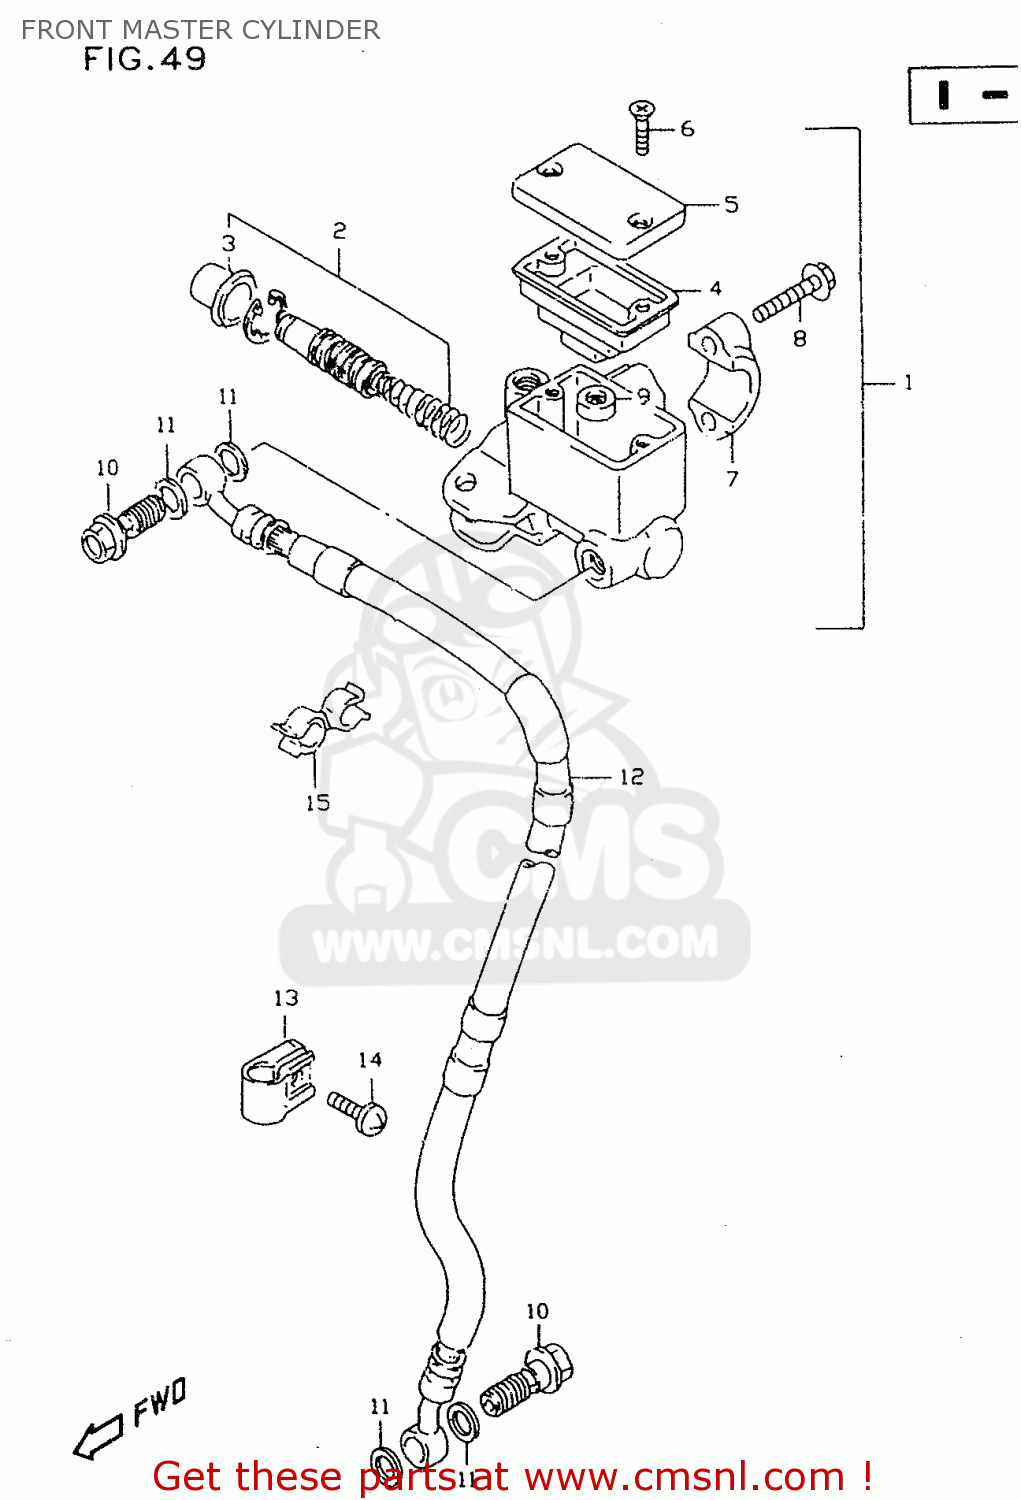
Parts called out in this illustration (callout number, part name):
1	CYLINDER ASSEMBLY,FRONT MASTER
2	PISTON/CUP SET
3	BOOT
4	DIAPHRAGM
5	CAP
6	SCREW
7	HOLDER
8	BOLT
9	SEPARATOR
10	BOLT UNION
11	WASHER(10X15X1.5)
12	HOSE,FR BRAKE
13	CLAMP,BRAKE HOSE
14	SCREW
15	CLIP
